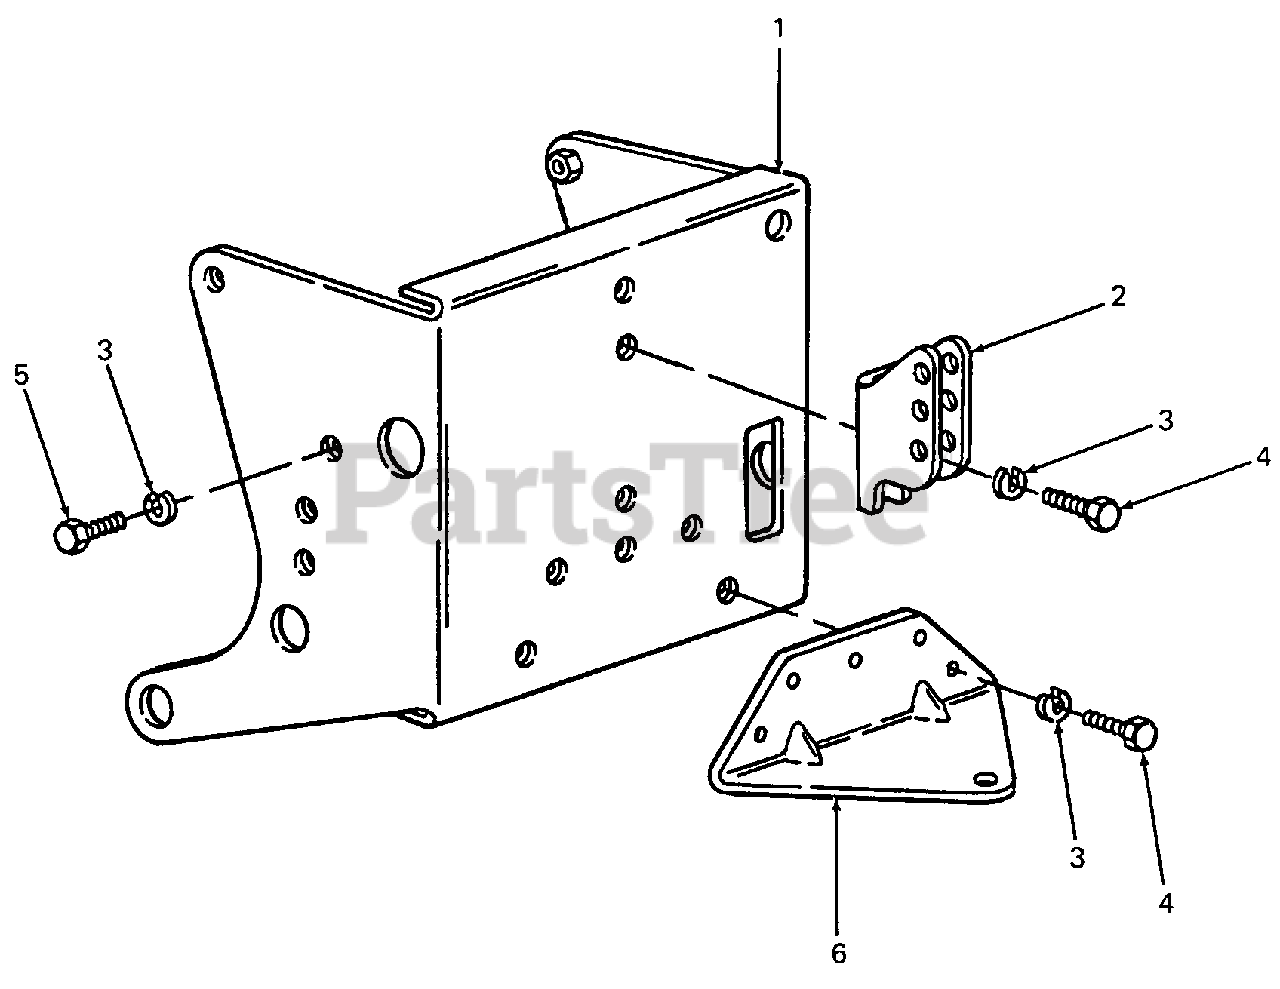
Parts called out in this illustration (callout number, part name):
1	Hitch Plate
3	Washer, Lock, 3/8
4	Screw, Hex Cap, 3/8-16 X .88 Lg GR5
5	Screw, Hex Cap, 3/8-16 X .75 Lg GR5
